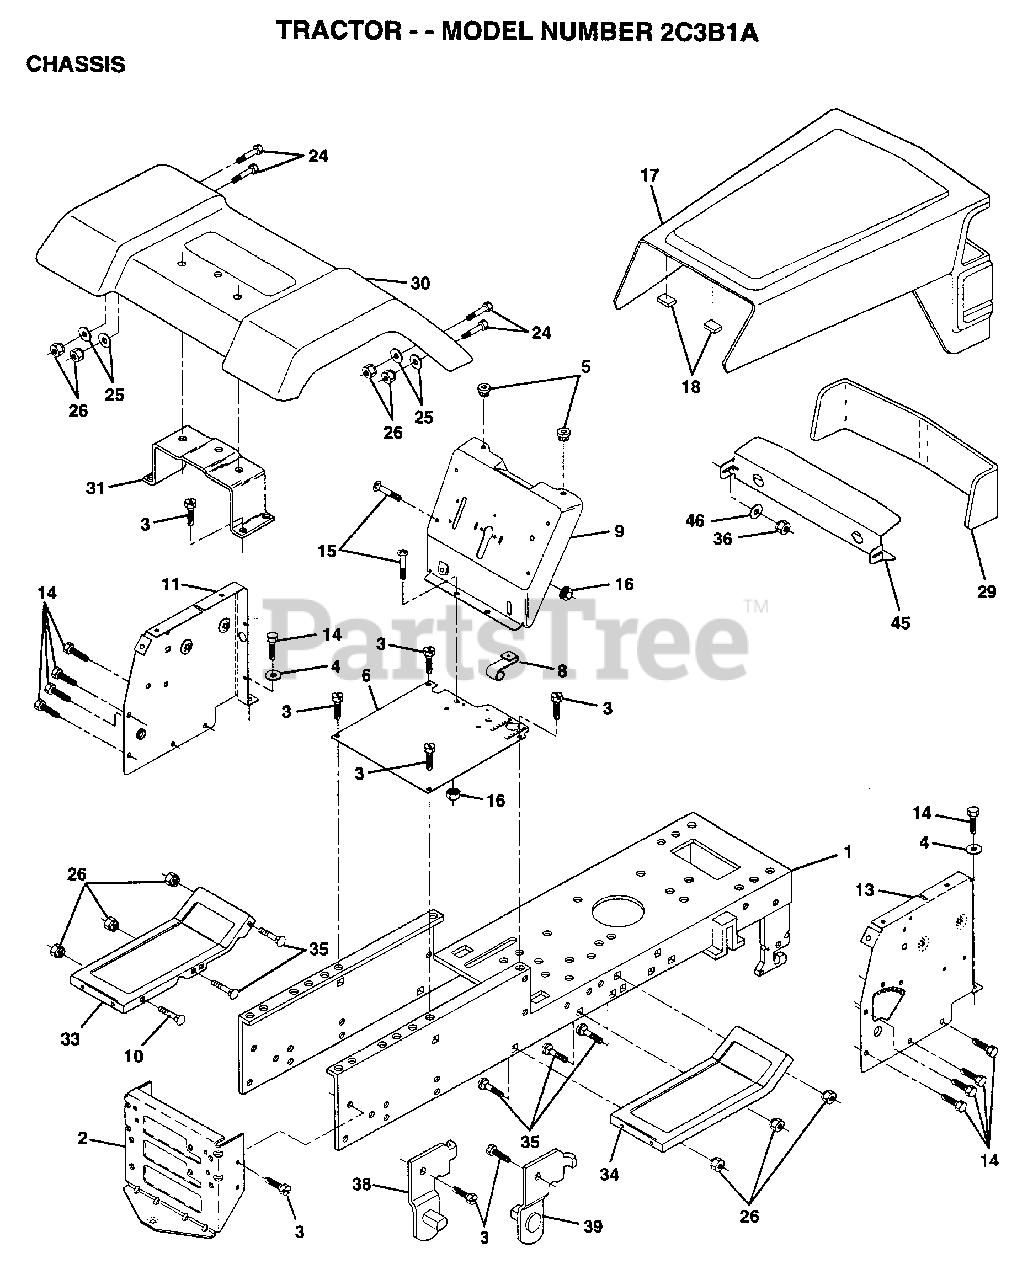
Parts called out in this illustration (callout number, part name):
1	CHASSIS.WLD.11GA
3	SCREW
4	WASHER
8	CLIP,INSULATOR
9	DASH.SLKSC.LT.1PC
11	DASH PANEL LH
14	SCREW LT
15	SCREW
17	HOOD/GRILL ASM
24	BOLT
25	WASHER
26	NUT
29	LENS SERVICE KIT
30	FENDER
31	BRKT FENDER
33	FOOTREST LH
34	FOOTREST RH
35	BOLT
36	PAL NUT LT
38	BRACKET ASM LH
39	BRACKET ASM RH
